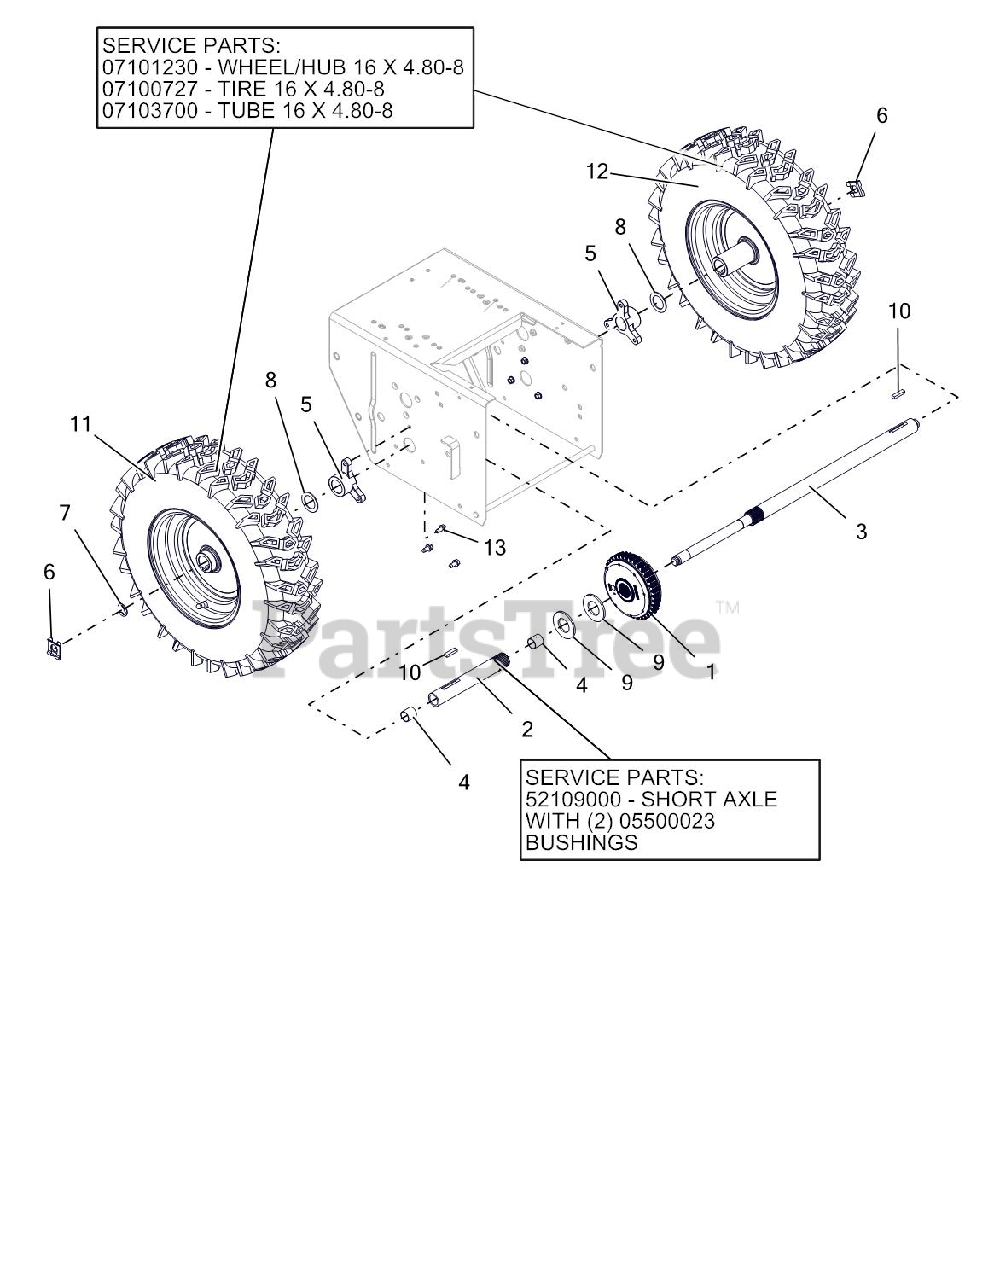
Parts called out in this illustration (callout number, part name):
1	DIFFERENTIAL, AUTOMATIC
2	BSHG-SLV .706X.764X.75 BRZ
2	AXLE,SHORT-DELUXE AUTO DIFF
2	AXLE, SHORT - W/BUSHINGS
3	AXLE,LONG-DELUXE AUTO DIFF
4	BSHG-SLV .706X.764X.75 BRZ
5	BUSHING, AXLE
6	CLIP, SNAP .625 DIA
7	RG-RTNG-EXT .625X.042
8	WSHR-FL-STL 1.010X1.505X.062YZ
9	WSHR-FL-STL- 1.062X2.0X.134 YZ
10	KEY-RECT .25X.188X1.00
11	TIRE/WHEEL,RH 16X4.8-8 DIFF T2
12	TIRE/WHEEL,LH 16X4.8-8 DIFF T2
13	SCR-TAP .25-20X.50 HWH TR YWZ
14	HUB, WHEEL-16X4.8-8
15	TIRE, 4.80-8 K478
16	TUBE
